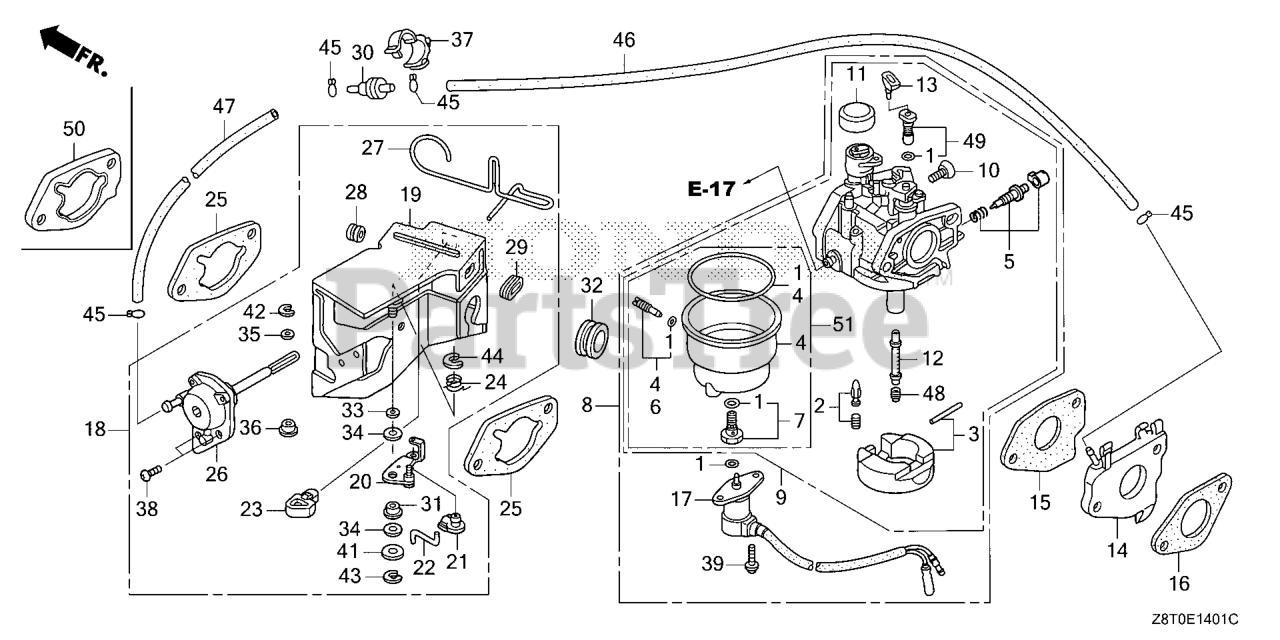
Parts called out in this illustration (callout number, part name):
1	GASKET SET
2	VALVE SET, FLOAT
3	FLOAT SET (CARBURETOR NO.)
4	CHAMBER SET, FLOAT
5	SCREW SET (CARBURETOR NO.)
6	SCREW SET, DRAIN (ADVENTURE GREEN) (CARBURETOR NO.)
8	CARBURETOR ASSY. (BEA5C B)
10	SCREW, THROTTLE STOP
11	CAP, CHOKE LEVER DUST
12	NOZZLE, MAIN
13	COLLAR, SET
14	INSULATOR, CARBURETOR
15	GASKET, CARBURETOR
16	GASKET, CARBURETOR INSULATOR
17	VALVE ASSY., SOLENOID
18	STAY ASSY., MANUAL CHOKE
19	STAY, SOLENOID
20	LEVER, CHOKE
21	JOINT, ROD
22	ROD, CHOKE
23	STOPPER, CHOKE ROD
24	SPRING, MANUAL CHOKE
25	GASKET, AIR CLEANER
26	DIAPHRAGM ASSY.
27	ROD, CHOKE CONTROL
28	GROMMET, CHOKE ROD
29	GUIDE, CHOKE ROD
30	VALVE, DASHPOT CHECK
31	BUSH, ARM PIVOT
32	GROMMET, FENDER
33	WASHER, CHOKE LEVER
34	SEAL, CHOKE LEVER
35	WASHER, THRUST (2.7X8)
36	COLLAR, LEVER
37	CLIP, WIRE HARNESS
38	SCREW, PAN (5X12)
39	SCREW-WASHER (5X12)
41	WASHER, PLAIN (5MM)
42	E-RING (2MM)
43	E-RING (4MM)
44	E-RING (7MM)
45	CLIP, TUBE (B7)
46	BULK HOSE, VACUUM (3.5X8000) (3.5X130)
47	BULK HOSE, VACUUM (3.5X8000) (3.5X130)
48	JET, MAIN (#95)
48	JET, MAIN (#98) Use from Engine SN BE87A A to BE87A A.
48	JET, MAIN (#102) (ADVENTURE GREEN) (CARBURETOR NO.)
49	JET SET, PILOT (#38)
50	SPACER, CARBURETOR
